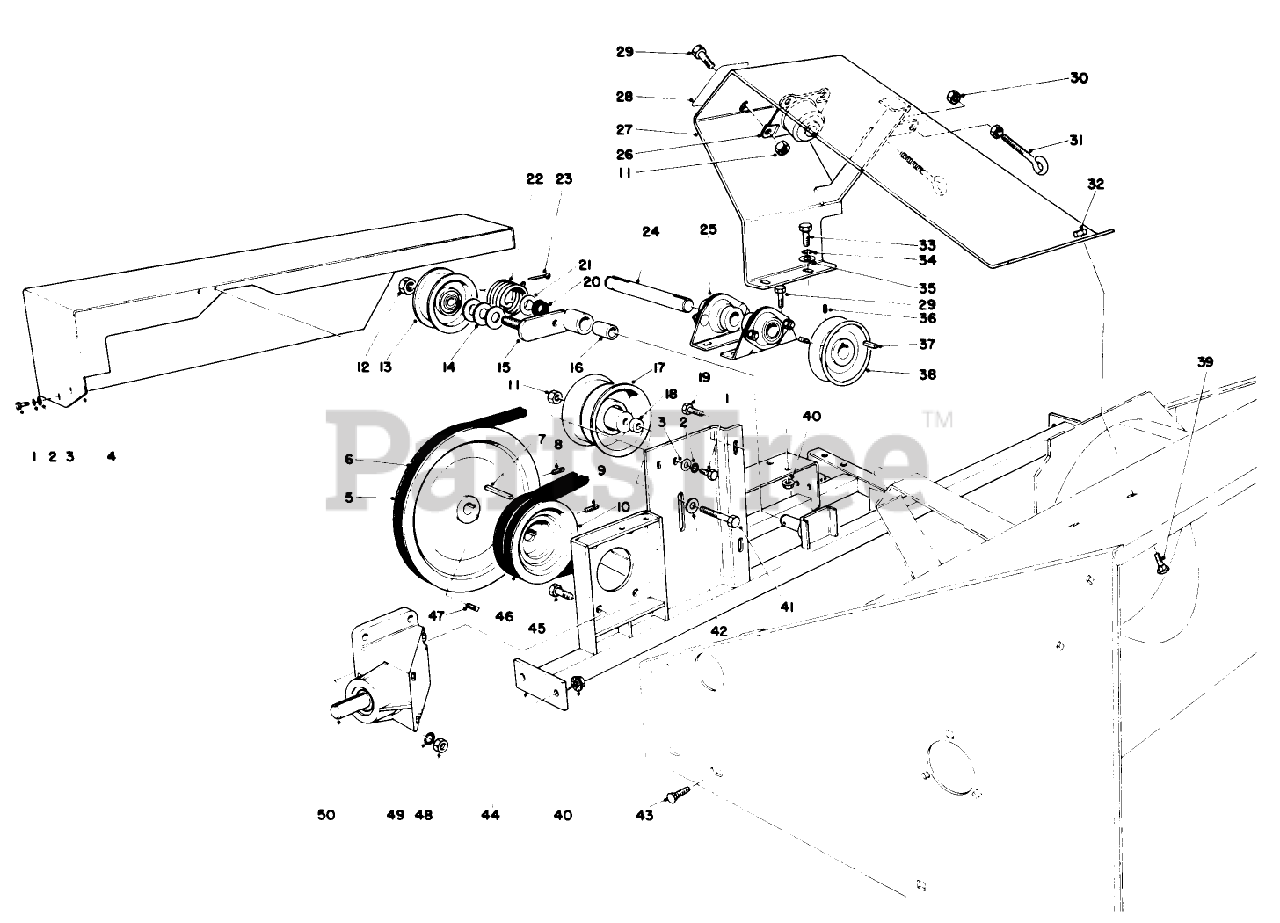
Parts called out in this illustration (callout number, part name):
1	Bolt
2	WASHER-LOCK
3	WASHER-FLAT
8	SCREW-SQH
9	SCREW-SET, SQH
11	NUT-LOCK, CONE
14	WASHER-FLAT
18	IDLER SPACER
19	SCREW-HH
23	PIN-COTTER
29	SCREW-HH
30	NUT-JAM
32	NUT-LOCK, NI
33	SCREW-HH
34	WASHER-LOCK
35	WASHER-FLAT
36	SCREW-SQH
39	BOLT-CARR
40	NUT-HHF, WHIZ
41	SCREW-HH
42	WASHER-FLAT
43	SCREW-CARR
45	SCREW-HH
47	SCREW-SET, SQH
48	NUT-HEX
49	WASHER-LOCK
50	ORDER COMPONENTS
